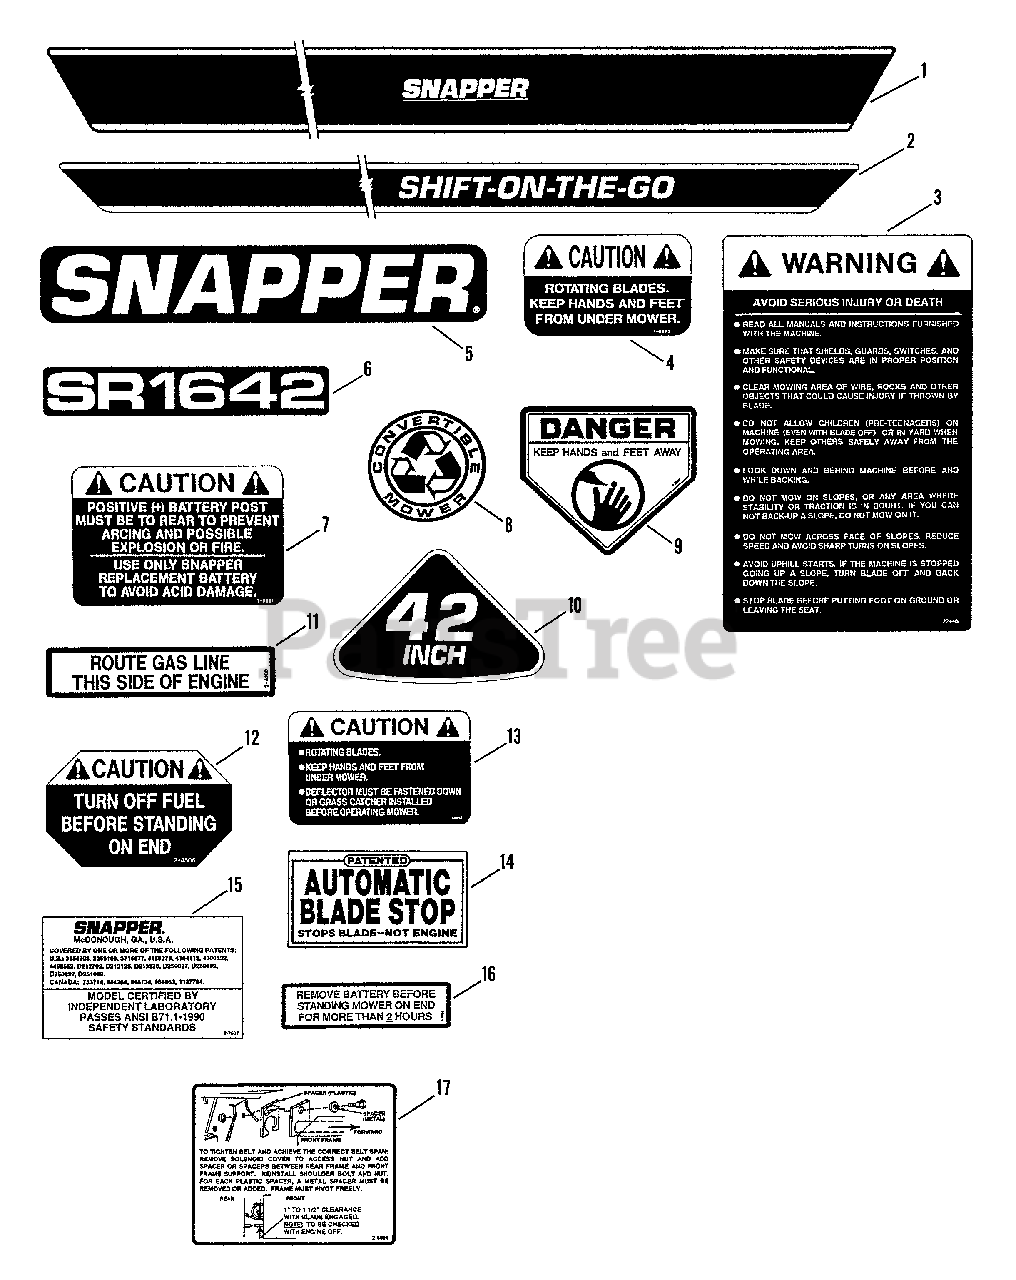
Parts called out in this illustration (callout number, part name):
1	DECAL, Banner (Blue) (42" Models)
2	DECAL, Bumper Stripe (Blue) (42" Models)
3	DECAL, Warning, Safety Instruction
4	DECAL, Caution, Rotating Blades
5	SNAPPER (Molded Logo)
6	DECAL, SR1642
7	DECAL, Caution, Battery
8	LOGO, Convertible (Blue) (42" Models)
9	DECAL, Danger
10	DECAL, 42 Inch
11	DECAL, Fuel Routing
12	DECAL, Fuel Shut-Off
13	DECAL, Caution
14	DECAL, Automatic Blade Stop
15	DECAL, Patent
16	DECAL, Battery Storage
17	DECAL, Belt Adjustment
